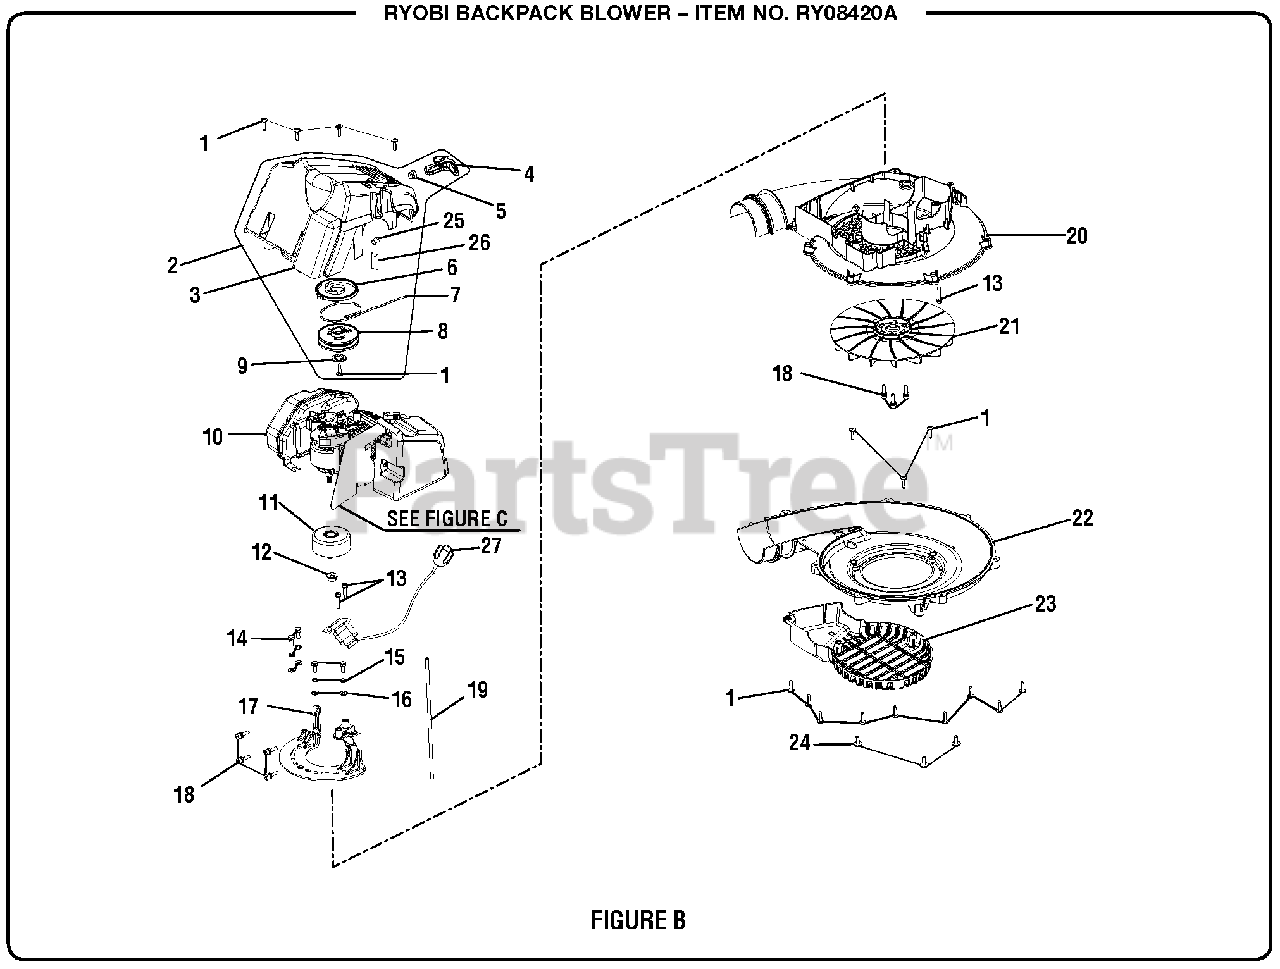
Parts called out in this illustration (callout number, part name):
1	Screw (10-14 x 19 mm, T-25 Torx)
2	Engine Cover w/Starter Assembly
3	Motor Cover
4	Starter Grip
6	Container Spring Assembly
7	Starter Rope
8	Solid Pulley
9	Starter Cap
10	Power Head
12	Lock Nut (M8)
13	Screw (M5 x 25 mm, T-25 Torx)
14	Screw (M6 x 14 mm)
15	Spring Washer (ID6.4 x 1.6t)
16	Washer (OD12.9 x ID6.6 x 1.2t)
17	Engine Mount
18	Screw (M5 x 0.8 in., 20 Torx)
20	Inner Volute
22	Outer Volute
23	Outer Volute Cover
24	Screw (10-14 x 16 mm)
26	Eyelet Support
27	Ignition Module
